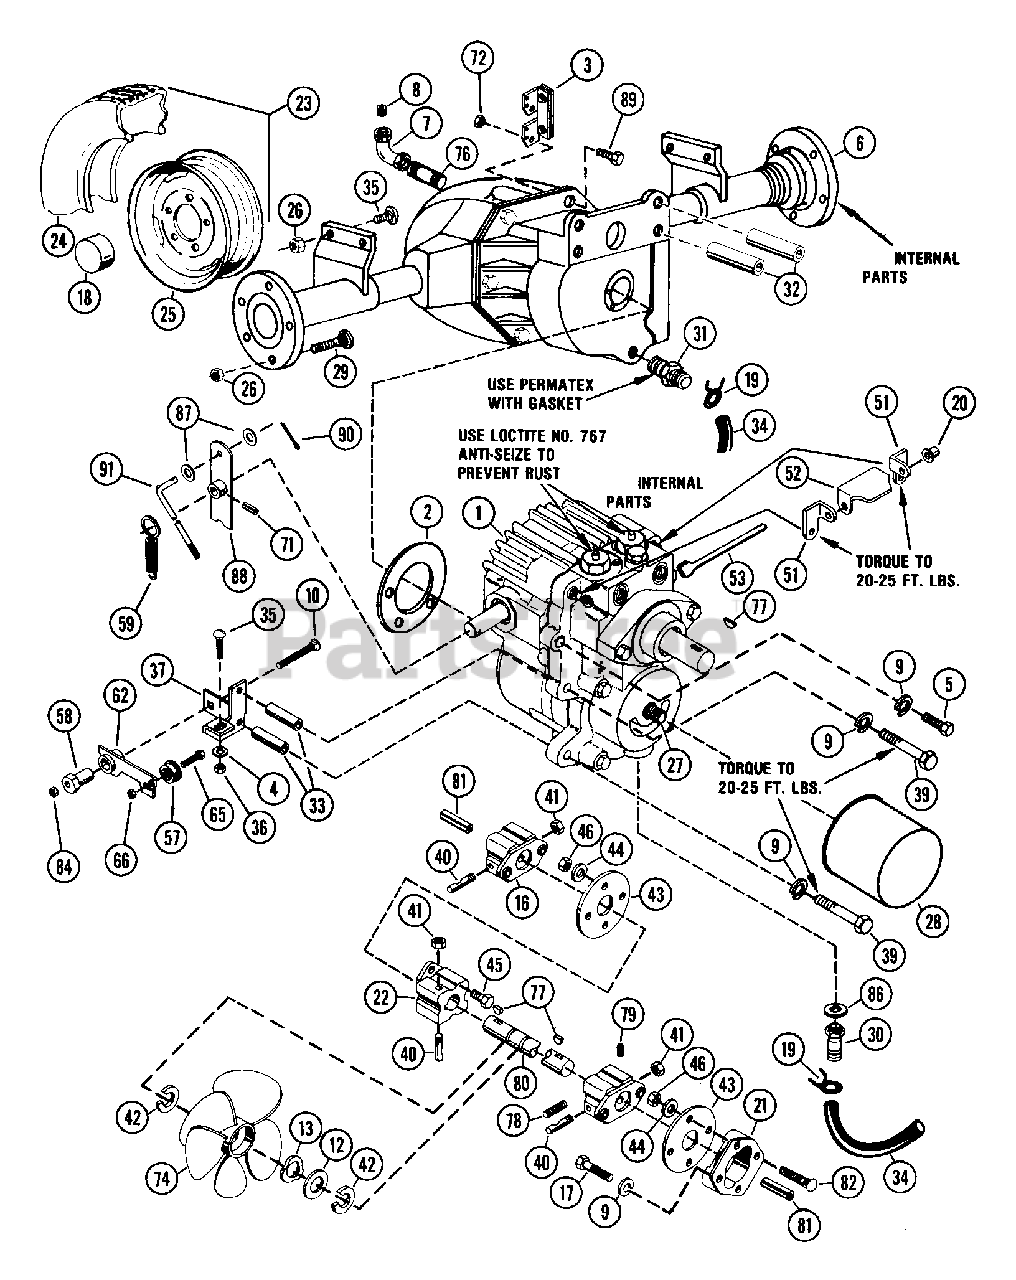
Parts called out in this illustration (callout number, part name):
1	SUNDSTRAND TRANSMISSION W/FILT
3	TORQUE BRACKET ASSEMBLY
4	WSHR-FL-STL .531X1.062X.095 PL
5	BLT-HEX .38-16X1.50 PL GR2
6	REAR AXLE AND SUPPORTS
7	ELBOW 1/2 X 90
8	PIPE PLUG
9	WSHR-LK .375X.094 MED PL
10	BLT-RDHDSQNK.31-18X2.25 PL
12	WSHR-FL-STL .754X1.000X.032
13	SPRING WASHER
16	DRIVE HUB - HYDRO
17	@BLT-HEX .38-16X.88 PL GR2
18	REAR HUB CAP
19	HOSE CLAMP #15 .906/.968
20	PUSH NUT, .312
21	DRIVE HUB - FLYWHEEL SINGLE
21	DRIVE HUB - FLYWHEEL TWIN
22	DRIVE HUB
23	10.50 X 23 REAR TIRE ASSY.
26	NUT-LUG .437-20 YWZC
28	OIL FILTER
29	CARRIER LUG BOLT
30	CONNECTOR
31	CONNECTOR 3/4
32	SPACER .379X.625X3.480
33	SPACER .379X.625X3.220
34	HOSE .62X.91X8.00
35	BLT-RDHDSQNK .50-13X1.25GR5PL
36	NUT-LK-CROWN .50-13 GR C PL
37	MOUNT WELDMENT
38	SHIFT ARM
39	BLT-HEX .38-16X5.00 PL GR2
40	LOCK STUD
41	NUT-LK TOP .375-16 GR C YWZC
42	RG-RTNG-EXT .750X.042
43	SPACER COUPLING
44	WSHR-FL-STL.344X.688X.065PL
45	BLT-HEX .31-18X.88 PL GR2
46	NUT-LK .312-18 GR A PL
51	SUPPORT
53	PIVOT ROD
57	BRG-BALL .250X.688X.312
58	ECCENTRIC
59	SG-TENS .080X.75X2.81 WLD 20
62	DETENT ARM
65	BLT-HEX .25-20X1.00 GR2
66	NUT-LK-CTR .250-20 PL
71	PIN-ROLL .250X1.38
72	NUT-LK-CTR .312-24 PL
76	PIPE NIPPLE 1/2 X 2
77	KEY-WDRF .188X.75X.313 SAE 9
78	LOCK STUD
79	SCR-SET .38-16X.50 SKHCUP OH
80	DRIVE SHAFT - HYDRO SINGLE
80	DRIVE SHAFT - HYDRO TWIN
81	PIN-GRV .313X.75 TP D
82	BLT-SERRDHD SL .31-18X.87 PL
83	DRIVE HUB
83	DRIVE HUB - TWIN SHAFT
84	NUT-LK-NYL.312-18 PL
86	O-RING .250X.943X.103
87	WSHR-FL-STL .323X.625X.062 PL
88	SHIFT ARM
89	BLT-HEX .31-18X1.50 PL GR5
90	PIN-COTR .09X.75 PL
91	NEUTRALIZER ROD
